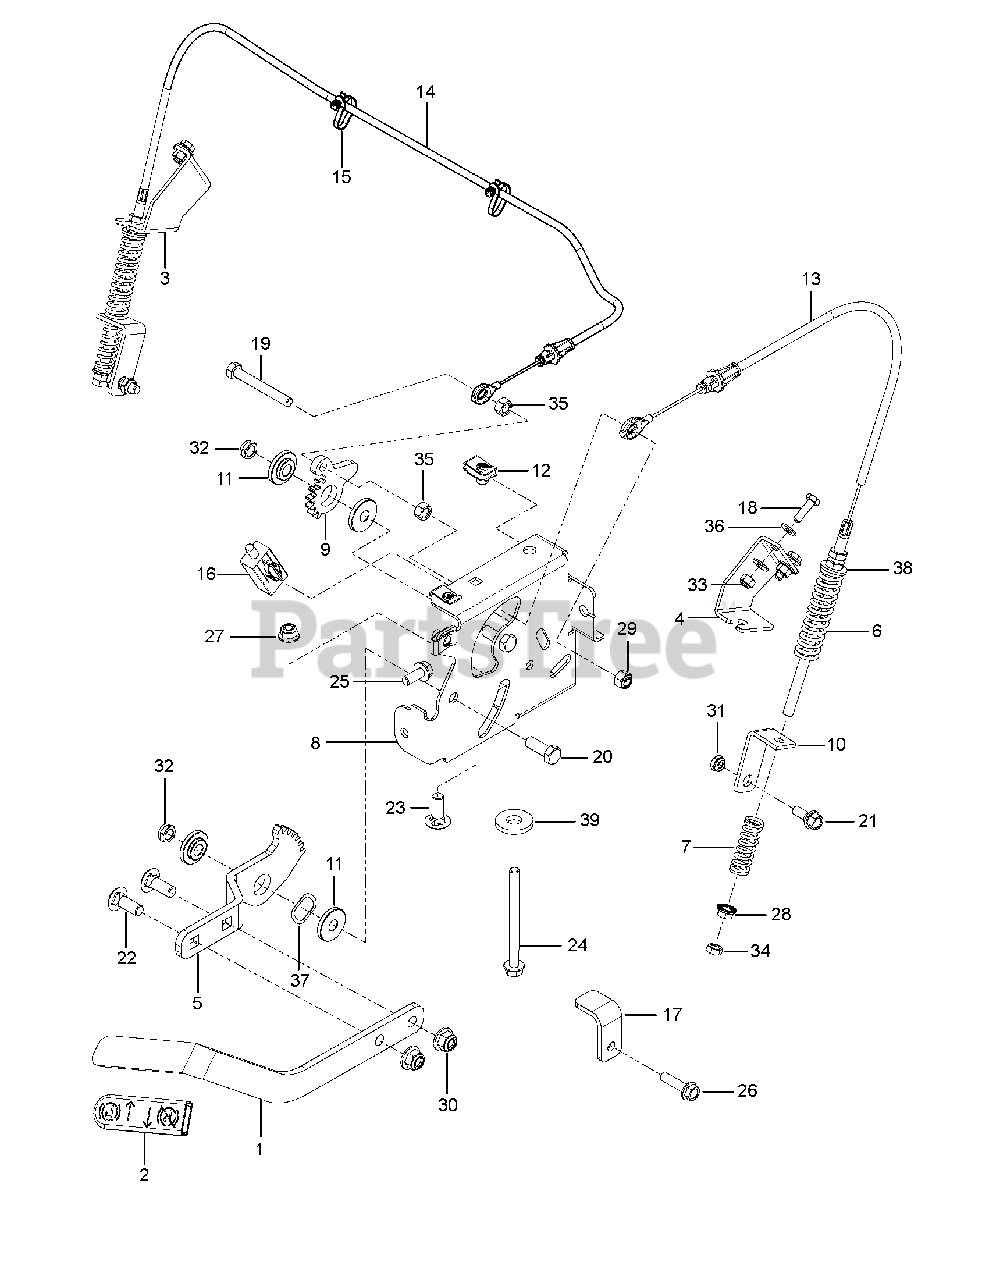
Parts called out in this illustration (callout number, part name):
1	ARM, BRAKE
2	GRIP, PARK BRAKE
3	Brake Bracket, RT Black MS-431
4	BRACKET BRAKE, LT BLACK MS-431
5	GEAR.INPUT.PARKING.BRAKE.MZ
6	SPRING, RETURN
7	SPRING, ENGAGEMENT
8	MOUNT.PNT.BRAKE.MZ.EDIP
9	GEAR OUTPUT;PARKING BRAKE;STAN
10	BRKT, BRAKE, BLK
11	BUSHING, BRAKE
12	U-CLIP 5/16-18 NUT RETAINER
13	CABLE.ASSY.BRAKE.CABLE.SHORT
14	CABLE.ASSY.BRAKE.CABLE.LONG
15	TIE WRAP, 8-3/8", W/CLIP
16	SWITCH.INTRLCK.CLUTCH.
17	BRACKET.PNT.LIMIT.ARM.BRK.EDIP
18	HCS 1/4-20X7/8 GR5
19	HCS 5/16-18 X 2 1/2 TPBLT
20	HCS 3/8-16X1.GRD.5.ZD
21	BOLT, SHOULDER
22	RHSNB 3/8C X 1
23	BOLT 5/16C X 3/4" CARRIAGE
24	HHFS 5/16-18 X 3 3/4
25	HHFS 5/16-18 X 3/4
26	HHFS 5/16-18 X 1.25 TPBLT GD 5
27	5/16-18 NYLOC FLANGE NUT
28	NUT 5/16C WHIZ
29	NUT 5/16 NYLOC
30	NUT 3/8-16 HEX FLG NYLOC ZD
31	5/16-18 THIN PROF NY
32	NUT HEX 3/8-16 NYLON, THIN
33	RP_NUT 1/4-20 NYLOC
34	NUT 5/16-18 HEX JAM ZD
35	NUT 5/16C HEX
36	WASHER 1/4 SAE
37	WASHER, .825 X 1.087, WAVE
38	WASHER 3/8 SAE FLAT
39	WASHER.9/16 X 1 3/8 X 12 GA.
